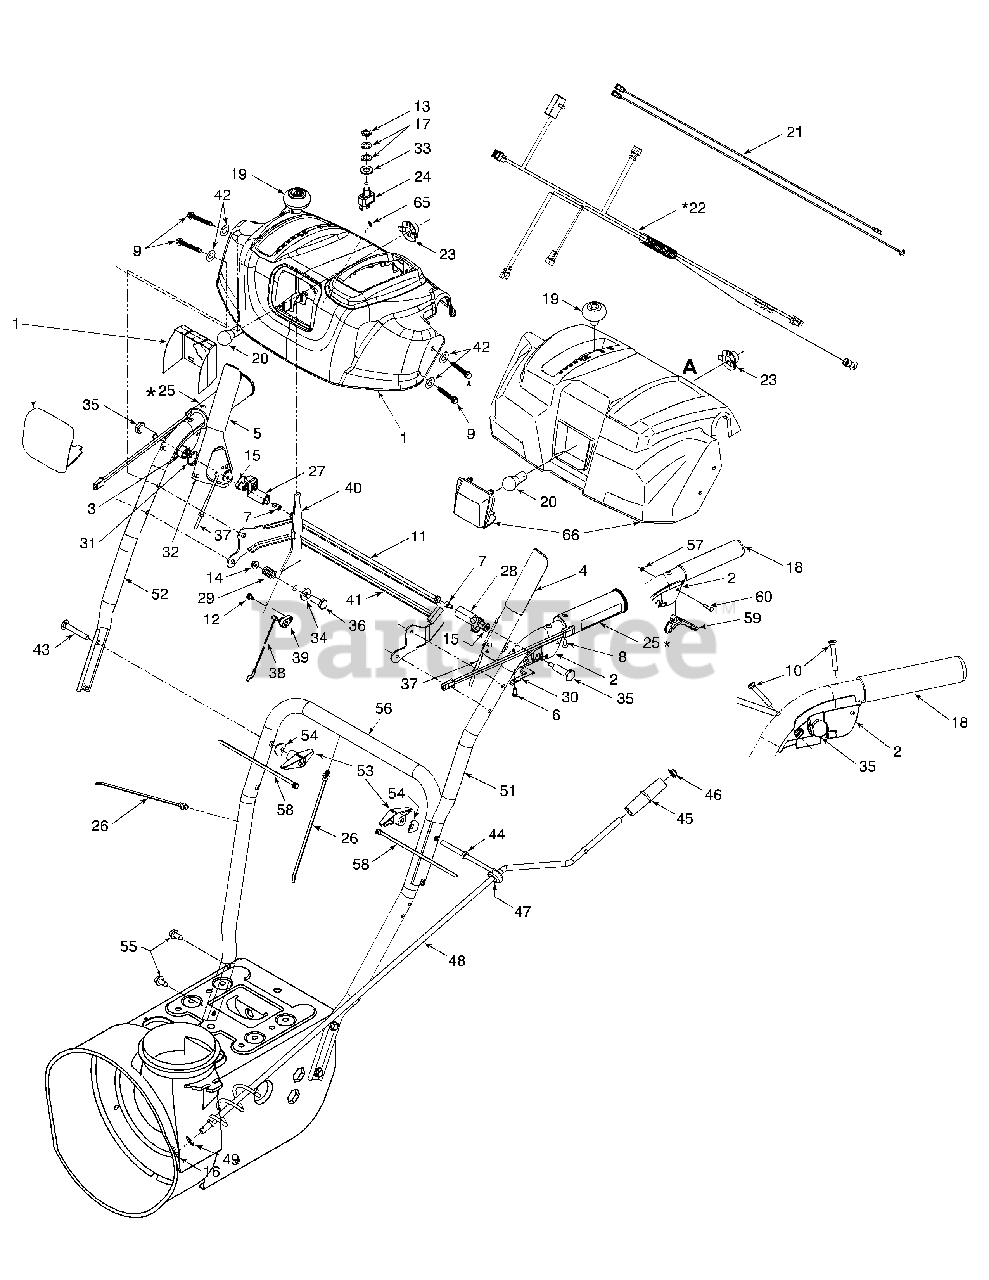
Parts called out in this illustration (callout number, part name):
1	Handle Panel Ass’y - Yellow
1	Handle Panel Ass’y - Black
1	Handle Panel Ass’y-Black w/Chute Control
2	LH Clutch Lock Handle Ass’y
3	RH Clutch Lock Handle Ass’y
4	Engagement Handle Assembly LH
5	Engagement Handle Assembly RH
6	Screw #8-16 x .50
7	Screw 1/4-20 x .375
8	Oval HD C-Sunk Scr #10 x 5/8
9	Hex TT-Tap Scr 1/4-20 x 1.75
10	Oval C-Sunk Hd Screw 10-24 x 1.375
11	Pivot Rod
12	Screw #10-16 x .50
13	Hex Nut
14	Hex L-Flanged Nut 1/4-20 Gr. F Nylon
15	Hex Shoulder Nut 1/4-20
16	Int. Cotter Pin .072 x 1.13" Lg.
17	Lock Ring - Toggle Switch
19	Shift Knob
19	Shift Knob - Yellow
20	Lamp #1295
21	Wire Harness
22	Heated Grip Wire Harness
23	Socket
24	Toggle Switch - Single Throw
25	Heated Grip
26	Cable Tie 19 x 8.39"
27	Lock Plate
28	Clutch Lock Cam
29	Compression Spring .38 ID x .88 Lg
30	Spring: Clutch Lock
31	Torsion Spring .8156 x .3038
32	Rubber Bumper
33	Flat Washer .469 ID x .88 OD x .063
34	Flat Washer .38 ID x .87 OD x .09
35	Shoulder Screw 1/4-20 x 1.345
36	Shoulder Screw .374 Dia. x 1.05 Lg.
37	Z Fitting
38	Selector Speed Cable
39	Cable Barrel Holder
44	Chute Crank Eye Bolt Special
45	Knob 1.0 x 3.2
46	Push Nut 3/8" Rod
47	Grom met
49	Flat Washer .406" I.D. x .75" O.D.
53	Handle Knob As sem bly
54	Saddle Wash. .320 ID x .937 OD
55	Hex Wash HD Lo Tap Scr 5/16 x .75
57	E Ring
58	Cable Tie
59	SteeringControl
60	Pin 3/16
65	E-Ring 0.76
66	Handle Panel Ass’y - Not used in this application
